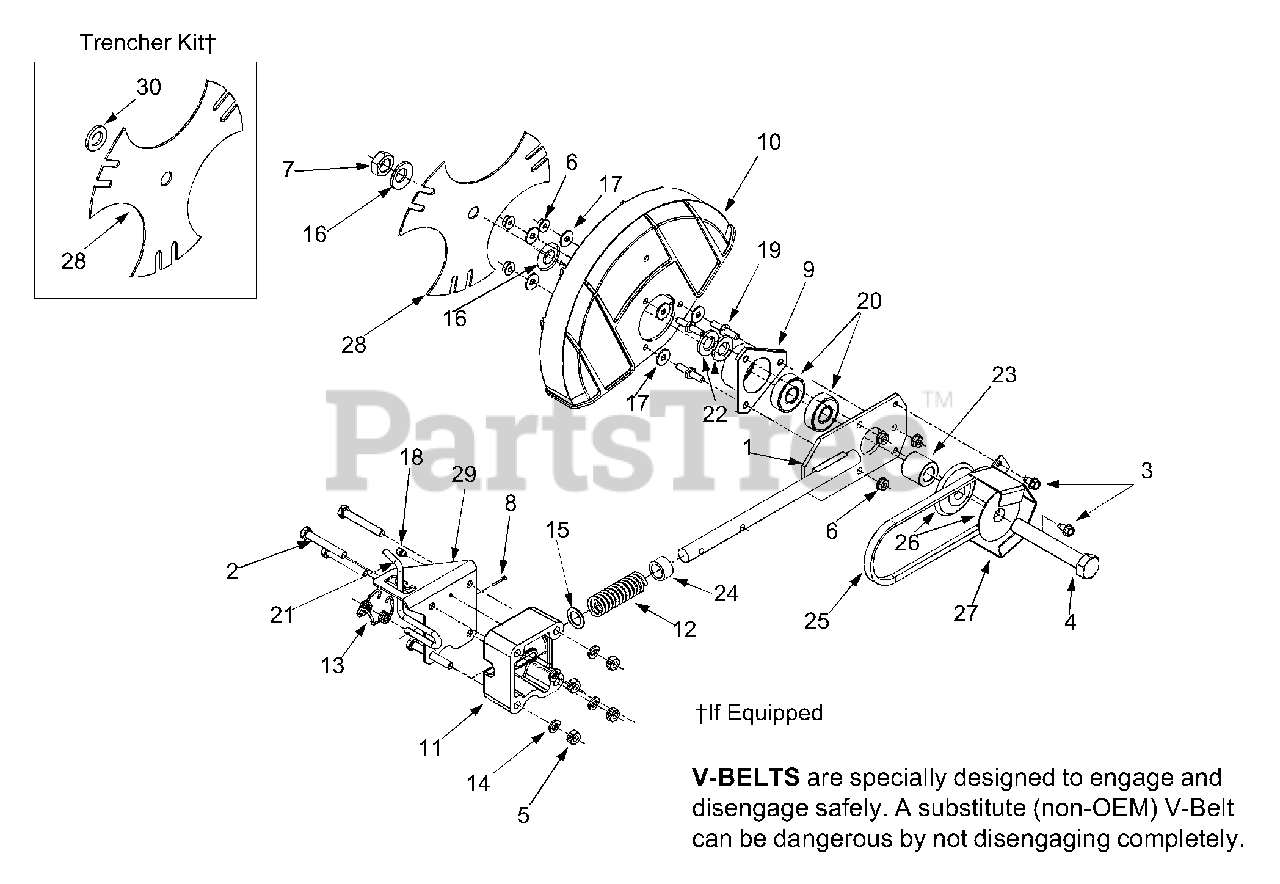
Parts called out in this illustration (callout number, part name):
1	Blade Plate Assembly
2	Hex Screw, 5/16-18
3	Self-tapping Screw, 1/4-20
4	Hex Screw, 5/8-18
5	Hex Lock Nut, 5/16-18
6	Hex Flange Nut, 1/4-20
7	Jam Nut, 5/8-18
8	Cotter Pin
9	Bearing Cup
10	Blade Guard
11	Bearing Block
12	Compression Spring
13	Double Torsion Spring
14	Lock Washer
15	Flat Washer,.64 ID x 1.24 x.06
16	Bell Washer,.63 ID x 1.2 OD
17	Flat Washer,.260 x.72
18	Lube Fitting, 3/16
19	Pin, 1/4-20
20	Bearing,.625 ID x 1.57 OD
21	Blade Adjustment Rod
22	Flat Washer
23	Spacer,.63 x 1.12 x 1.06
24	Spacer,.632 ID x.875 OD
25	Belt
26	Sheave
30	Flat Washer
